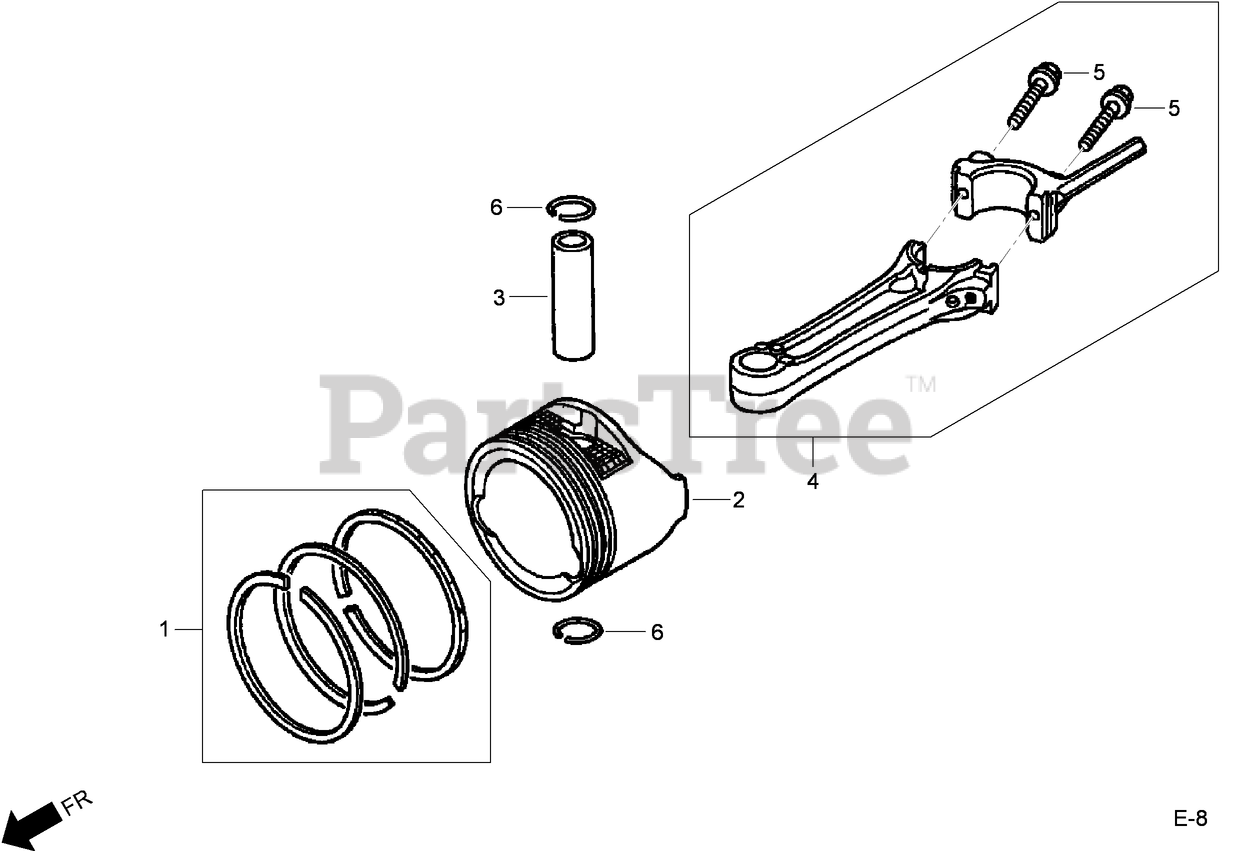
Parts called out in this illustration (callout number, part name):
1	PISTON RING SET (STD) (TEIKOKU) (engine serial numbers starting at 5383515)
2	PISTON
3	PIN-PISTON
4	CONNECTING ROD ASM
5	BOLT-ROD, CONNECTING
6	CLIP-PIN, PISTON (13MM)
